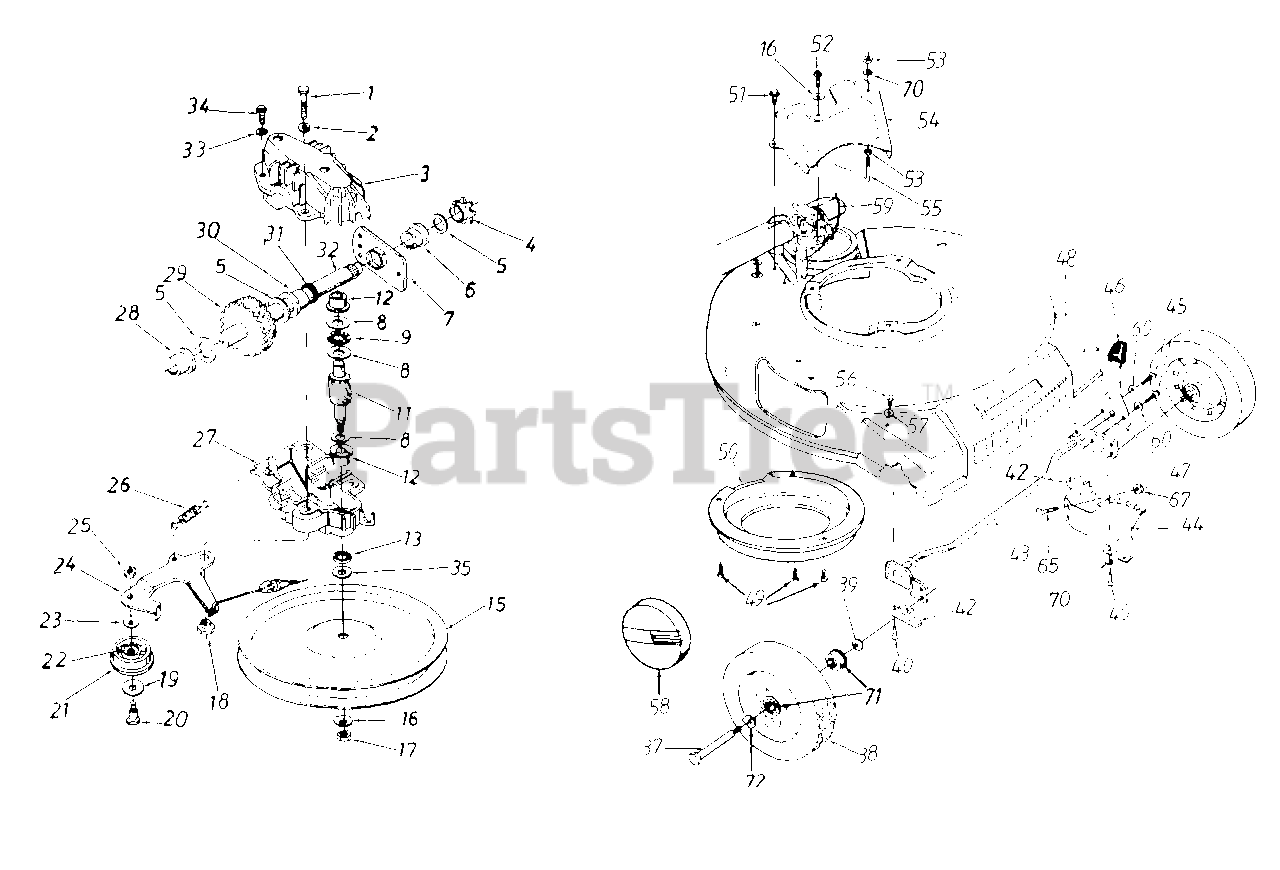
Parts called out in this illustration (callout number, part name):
1	Hex Patch Bolt 1/4-20 x 1.25"
2	L-Wash. 1/4" I.D.
3	Upper Hsg. Half
4	#48 Sprocket 7 T x 1/2 Pitch
5	Fl-Wash. 5/8" I.D. x .030
6	Hex Flange Brg..631" I.D.
8	Thrust Wash..382" I.D. x .70" O.D.
9	Thrust Bearing .375" I.D. x .812" O.D.
11	11 Tooth Pinion Shaft
12	Flange Bearing
13	Oil Seal
15	Fl-Pulley 5.06" O.D.
16	Bell-Wash..265" I.D. x .75"
17	Hex L-Nut 1/4-28 L.H. Thd.
18	Shld. Spacer .375" Dia. x .170
19	Fl-Wash..390" I.D. x 1.0"
20	Shld. Bolt .375" Dia. x .40"
21	Fl-Idler Plastic 1.50" Dia.
22	Needle Brg..375" x .31
24	Idler Brk't. Ass'y.
25	Hex Patch L-Nut 1/4-28 Thd.
26	Extension Spring 1.12" Lg.
27	Lower Hsg. Half
28	Flange Bearing .566 Dia.
29	33 Tooth Helical Gear
30	Flange Bearing .629 Dia.
31	Oil Seal .625 Dia.
32	Gear Sprocket Shaft
33	L-Wash. #10 I.D.
34	Hex B-Tap Scr. #10 x .62"
35	Hex Washer .26" x .88"
37	Front Axle Bolt
38	Wheel Ass'y. Comp. (Gray Rim)
39	Bell-Wash .380" I.D. x .88
40	Hex Wash. Hd. Scr. 1/4 x 1" Lg.
42	Block Bushing
45	Hex TT- Tap Scr. 1/4-20 x .38"
46	Knob
47	Spring Lever
48	Plastic Front End (Black)
49	Hex B-Tap Scr. 1/4" x .38"
52	Hex Wash Hd. B-Tap Scr. 1/4 x .62" (Spec.)
53	Hex Nut 1/4-20 Thd.
56	Torx Truss Hd. Scr. 5/16 x .75"
57	Bell-Wash. 345" I.D. x .88"
58	Hub Cap (See Chart)
59	S.P. Cable
60	External L-Wash. 1/4" I.D.
65	Carr. Bolt 1/4-20 x .5" Lg.
67	Hex Flange L-Nut 1/4-20 Thd.
70	L-Wash. 1/4" I.D.
71	Wheel Bearing
